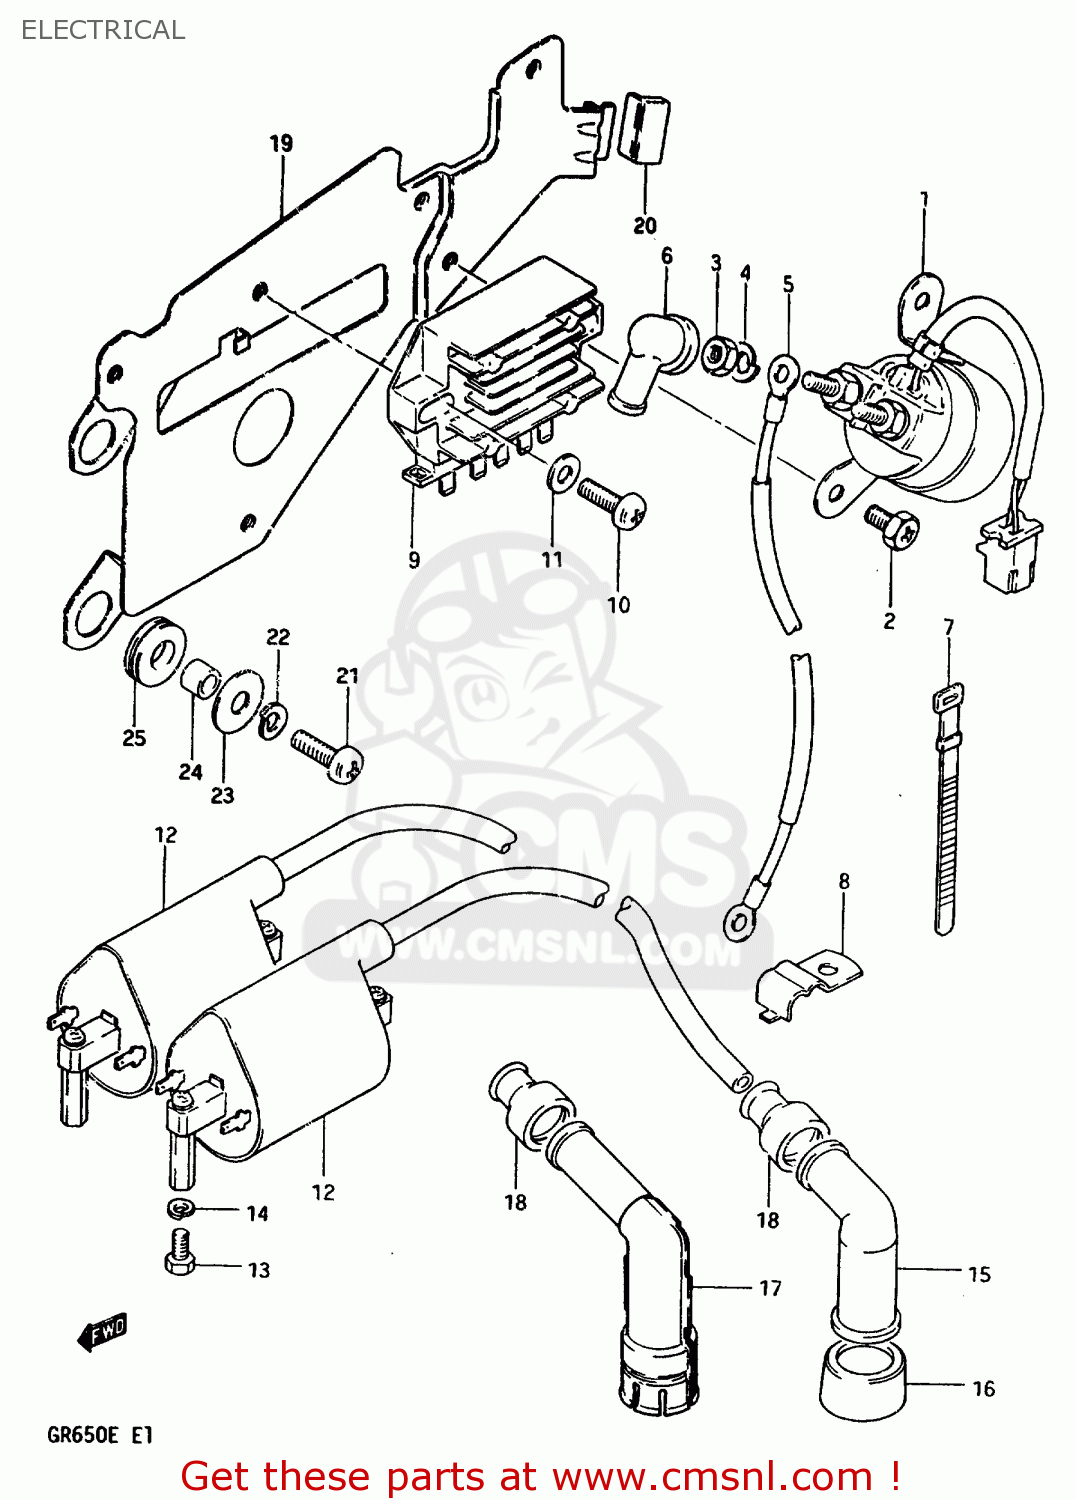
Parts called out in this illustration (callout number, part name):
1	RELAY ASSEMBLY,STARTING MOTOR
2	SCREW(6X10)
3	NUT
4	WASHER,LOCK
5	CABLE,STARTING MOTOR
6	CAP,STARTER MOTOR TERMINAL
7	CLAMP(L:80)
8	CLAMP
9	RECTIFIER ASSEMBLY
10	SCREW
11	WASHER
12	COIL ASSY,IGNITION
13	BOLT
14	LOCK WASHER
15	CAP ASSY,SPARK PLUG
16	SEAL,SPARK PLUG
17	CAP, SPARK PLUG
18	SEAL,SPARK PLU
19	PLATE, PARTS HOLDER
20	CUSHION,FRAME COVER
21	SCREW
22	WASHER,LOCK
23	WASHER
24	SPACER (6.3X9.1X6.7)
25	CUSHION
